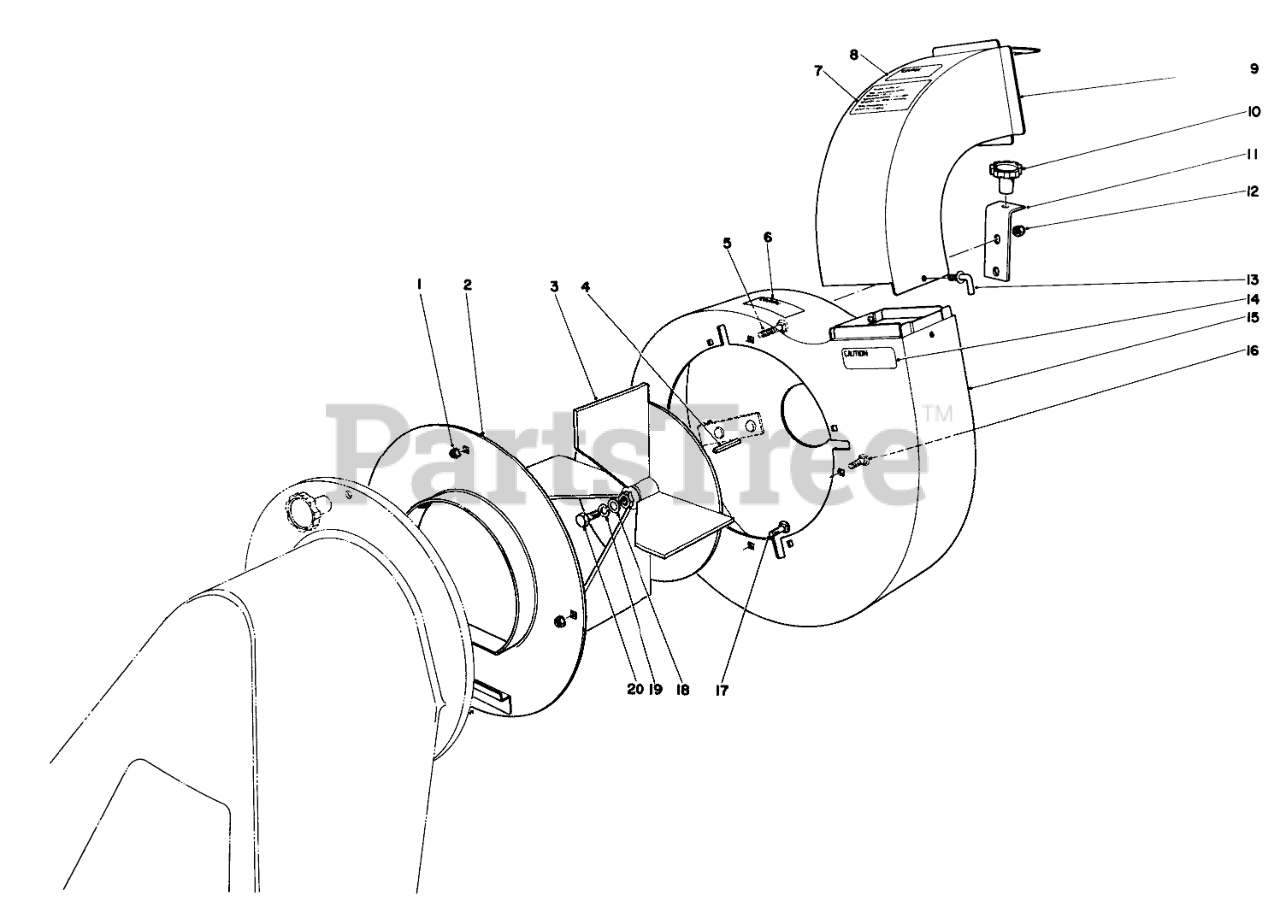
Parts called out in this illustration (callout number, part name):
1	NUT-KEPS
2	Blower Cover
3	Fan
4	KEY-SQUARE
5	SCREW-CARR
6	Decal-Caution
7	TORO ADVER DECAL
8	DECAL CAUTION BAG
9	Chute-Vacuum
11	Mounting Bracket
12	NUT-LOCK, NI
13	ADJ SCREW 1/4-20X 3/4
14	WARNING DECAL
15	Blower Housing
16	SCREW-CARR
17	SCREW-CARR
18	WASHER-FLAT
19	WASHER-LOCK
20	SCREW-HH
